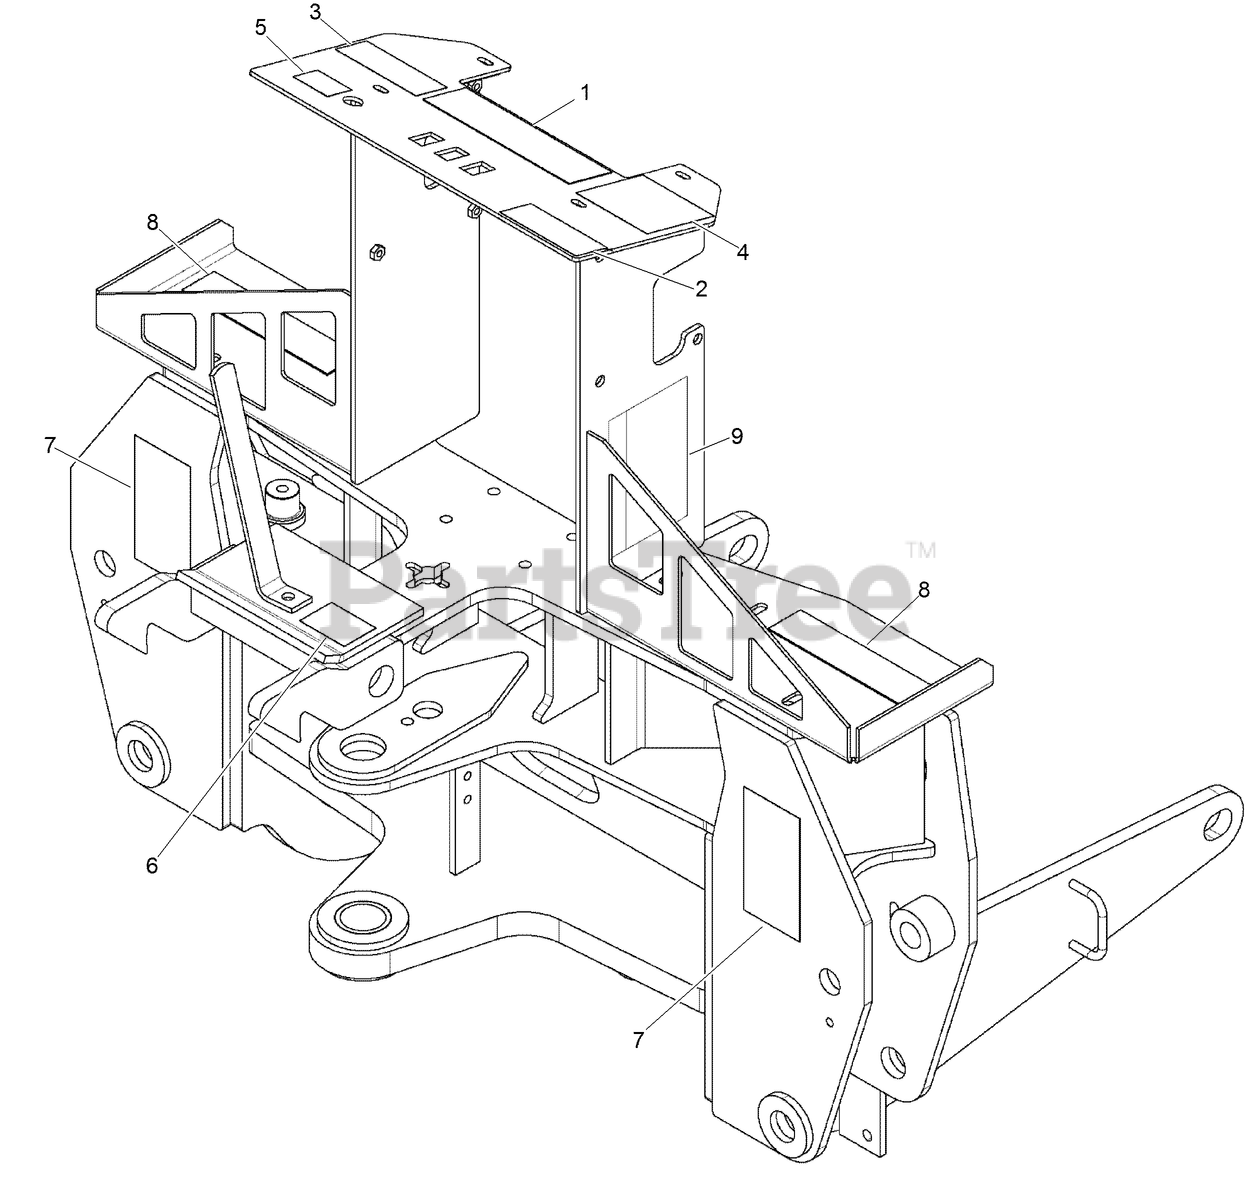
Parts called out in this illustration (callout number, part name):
1	DECAL-Backhoe Control Pattern
2	DECAL - Danger, Backhoe Crush Hazard
3	DECAL - Backhoe Stabilizer
4	DECAL - Warning, Backhoe Lifting
5	DECAL-Engine Shut-Off
6	DECAL-BH Transport Lock
7	DECAL - Danger, Backhoe Crush Hazard
8	TAPE - Anti-Skid
9	DECAL - Warning, Backhoe Operation
